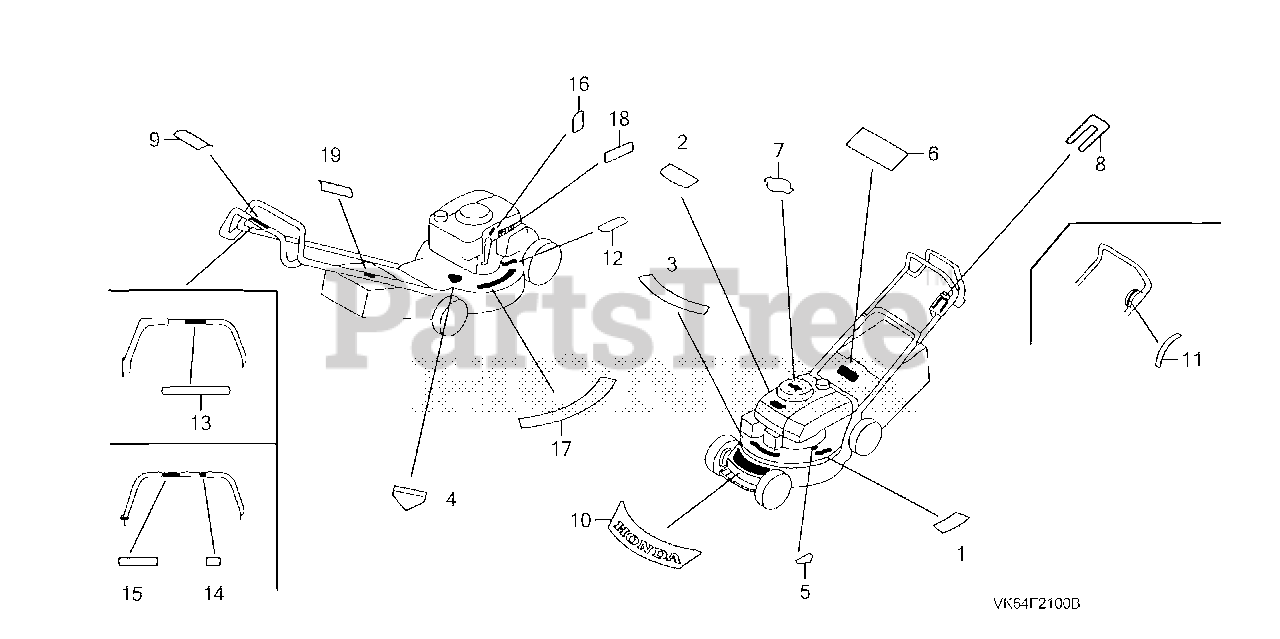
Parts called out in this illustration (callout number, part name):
2	MARK, EMBLEM
4	CAUTION C, HOUSING
6	LABEL, WARNING (ENGLISH)
8	MARK, THROTTLE INDICATION (ENGLISH)
9	MARK, CLUTCH INDICATION (ENGLISH)
10	MARK, HONDA
12	LABEL, HEAT WARNING
13	MARK, BLADE CONTROL (ENGLISH)
16	MARK, OIL CAUTION
17	MARK, SALES POINT
18	MARK, OIL RECOMMENDED
19	MARK, HOLD POSITION
